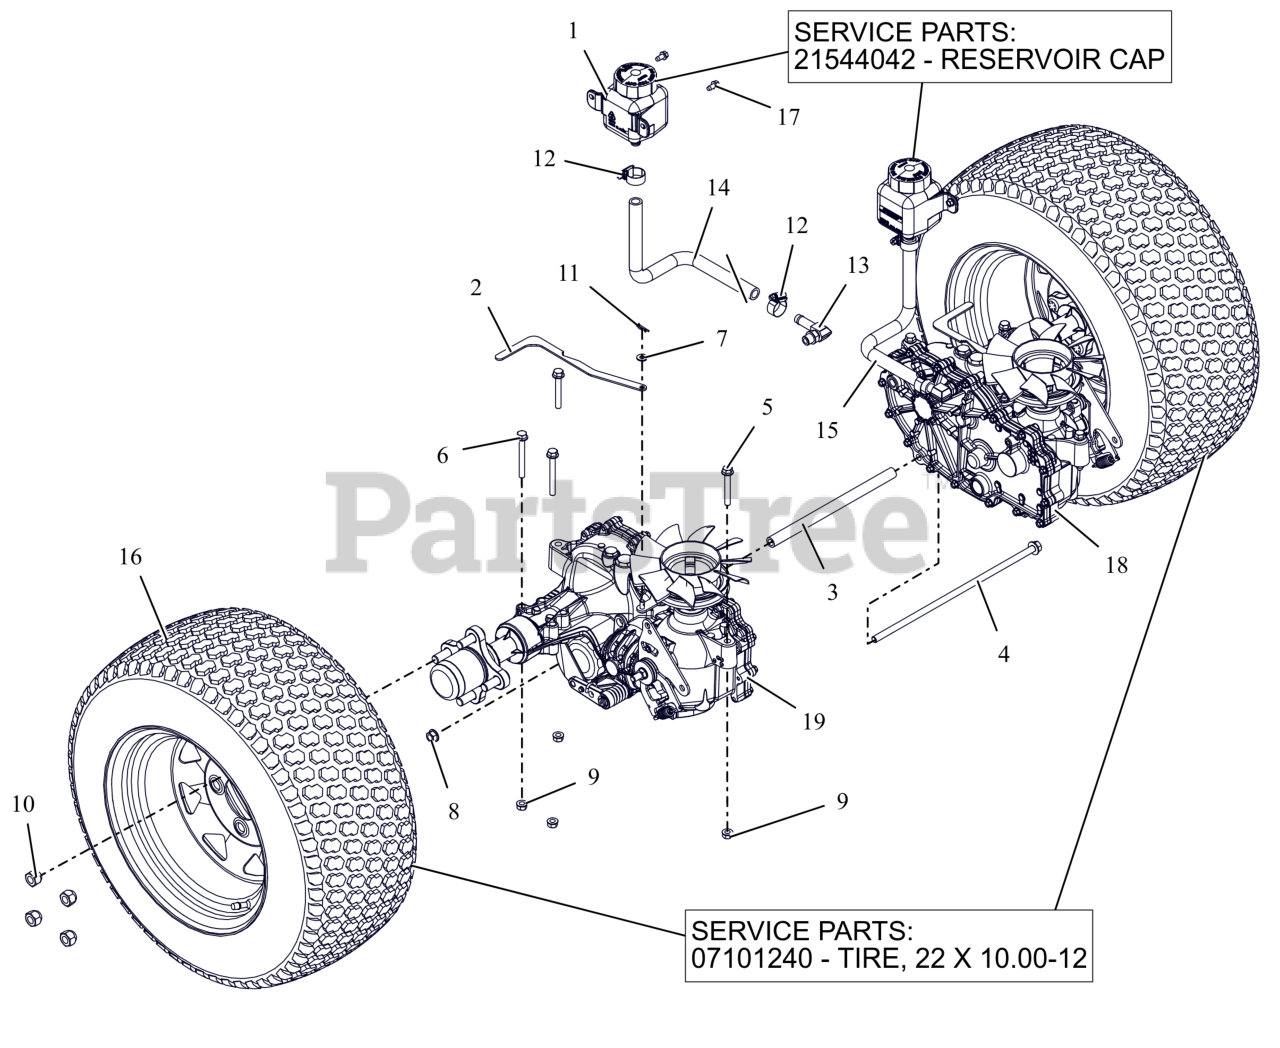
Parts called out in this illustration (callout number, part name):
1	TANK, EXPANSION
1	CAP, HYDRO RESERVOIR REPLAC.
2	BRKT, VALVE DUMP
3	SPCR,TRANS. .406IDX.63ODX9.95L
4	BLT,HEX-FLG .38-16X13 G5 ZCC
5	BLT,HEX-FLG .31-18X2.25 G5 ZCC
6	BLT,HEX-FLG .31-18X2.75 G5 ZCC
7	WSHR,FLT .281X.625X.065 ZCC
8	NUT-LK-TOP-FLG .38-16 ZC120
9	NUT,LK-CTR-FLG .31-18 GF ZCC
10	NUT, WHEEL .50-20 ZCC
11	PIN, HAIR #225 .072X1.09
12	CLAMP,.88 DIA. HOSE
13	FITTING, HYD (90 DEG)
14	HOSE, FORMED EXPANSION -HD RH
15	HOSE, FORMED EXPANSION -HD LH
16	ASM, WHL/TIRE 22X10.00-12 K500
16	TIRE, 22X10.00-12
16	VALVE STEM ASS'Y
16	TIRE TUBE 22,23,24/8.50/9.50/10.00/10.50/12.00-12 4 PLY TR13 STRAIGHT VALVE
17	SCR-TAP .25-20X.50 HWH ZCC
18	TRANSAXLE, ZT3100 - LH
19	TRANSAXLE, ZT3100 - RH
